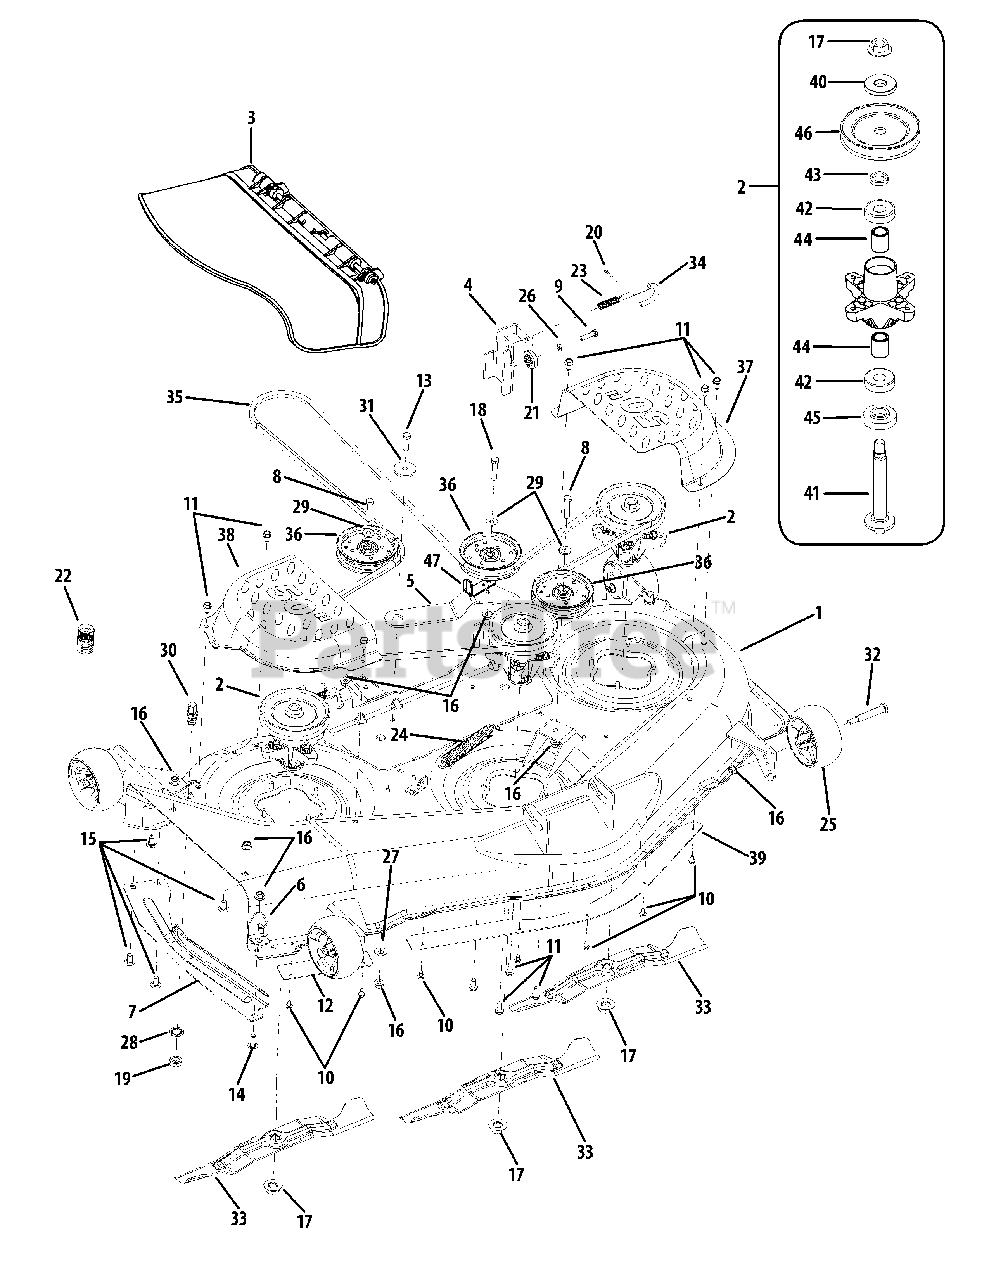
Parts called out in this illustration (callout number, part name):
1	Deck Housing
2	Spindle Assembly
3	Discharge Chute Assembly
4	Deck Hanger Bracket
5	Idler Arm
6	Stop Bracket
7	Finger Guard
8	Hex Cap Screw, 3/8-16 x 1.75
9	Hex Cap Screw, 5/16-18 x 1.25
10	Hex Washer Head Screw, 1/4-20 x .5
11	Hex Washer Head Screw, 5/16-18 x .750
12	RH Skirt
13	Hex Cap Screw, 3/8-16 x 1.25
14	Hex Screw, 3/8-16 x 1.00
15	Carriage Screw, 3/8-16 x .75
16	Hex Insert Flange Lock Nut, 3/8-16
17	Hex Flange Nut, 5/8-18
18	Hex Cap Screw, 3/8-16 x 2.00
19	Hex Nut, M16-1.5
20	Cotter Pin, 1/8 x 1.25
21	Deck Adjustment Gear
22	Water Nozzle Adapter
23	Compression Spring, .535 x 1.751
24	Extension Spring, .94 x 6.74
25	Deck Ball Wheel, 5.0
26	Lock Washer, 5/16
27	Bell Washer, .45 x 1.0 x .062
28	Internal Tooth Lock Washer, 5/8
29	Flat Washer, .38 x .93 x .110
30	Deck Wash Nozzle
31	Shoulder Spacer, .884 x .190
32	Shoulder Screw, .5 x 2.5 x 3/8-16
33	Blade, 2 in 1, 17.9
34	Deck Hanger Rod
35	V-Belt Type A Sec x 134
36	Idler Pulley, 4.25 Dia
37	Belt Cover, LH
38	Belt Cover, RH
39	Center Skirt
40	Flat Washer, .76 x 1.50 x .12
41	Spindle Shaft, 5.75
42	Ball Bearing
43	Spacer, .79 x 1.25 x .175
44	Spacer, .80 x 1.10 x 1.32
45	Spacer, .79 x 1.82 x .55
46	V-Type Pulley, 5.39
47	Bracket, Belt Guard
